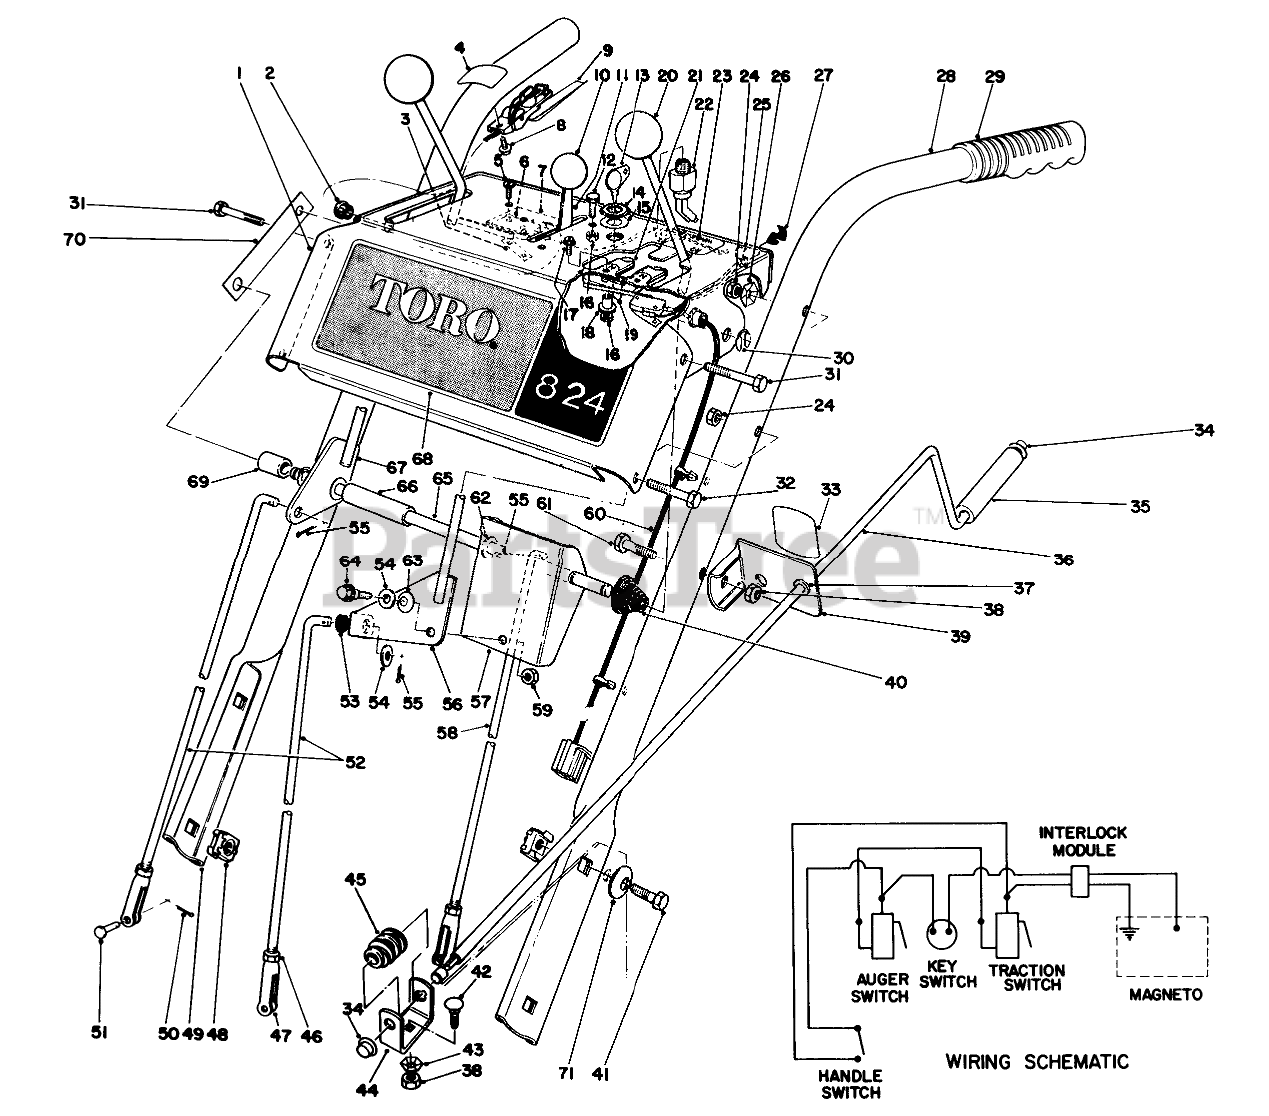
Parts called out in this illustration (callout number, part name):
1	ESCUTCHEON PLT B
2	BUSHING NYLON
3	NUT-SPEED
4	INTERLOCK DECAL
5	SCREW-SPH
6	SWITCH-MICRO
7	SWITCH MTG PAD
8	SCREW
9	INTERLOCK HDLE SWITCH
10	CONTROL KNOB
11	THROTTLE CONTROL
12	HEX HEAD SEMS 10-24X1/2
13	Key
14	NUT-HH
15	WASHER-TOOTH, INTERNAL
16	NUT-LOCK, NI
17	10-24 X 7/8 RND HD MS
18	INTERLOCK SPACER
19	INTERLOCK SPRING
21	Slide Interlock
22	Key Switch
23	INSTRUCTION DECAL
24	NUT-LOCK, CONE
25	WIRE CLAMP
26	Washer
27	Mounting Stud
28	LEFT HANDLE
29	Grip Handle
30	RING-CLIP
31	SCREW-HH
32	SCREW-HH
33	CHUTE DECAL
34	RETAINER-PUSH ON
35	GRIP-CONTROL, CHUTE
36	CHUTE CONTROL ROD
37	Bushing
38	NUT-LOCK, NI
39	Chute Control Rod Mounting (Incl. Ref. #34 & 38)
40	CONICAL SPRING
41	SCREW-HH
42	BOLT-CARR
43	WASHER-LOCK
44	BRACKET-WORM
45	GEAR-WORM, CHUTE
46	NUT-HJ
47	CLEVIS
48	Retained Nut
49	HANDLE RIGHT
50	PIN-COTTER
51	PIN-CLEVIS
52	SPEED SELECTOR ROD
53	GROMMET-RUBBER
54	WASHER-FLAT
55	PIN-COTTER
56	SHIFT LEVER WA
57	SHIFT BRACKET
58	TRACTION CONTROL ROD
59	NUT-LOCK, CONE
60	WIRE HARNESS INTERLOC
61	SCREW-HH
62	WASHER-FLAT
63	7/16 SPRING WASHER
64	SHOULDER SCREW
65	PIVOT ROD
66	SHIFT LEVER SPACER
67	LEVER WA
68	ESCUTCHEON DECAL
69	AUGER LEVER SPACER
70	ESCUTCHEON SUPT STRAP
71	WASHER-SPRING
